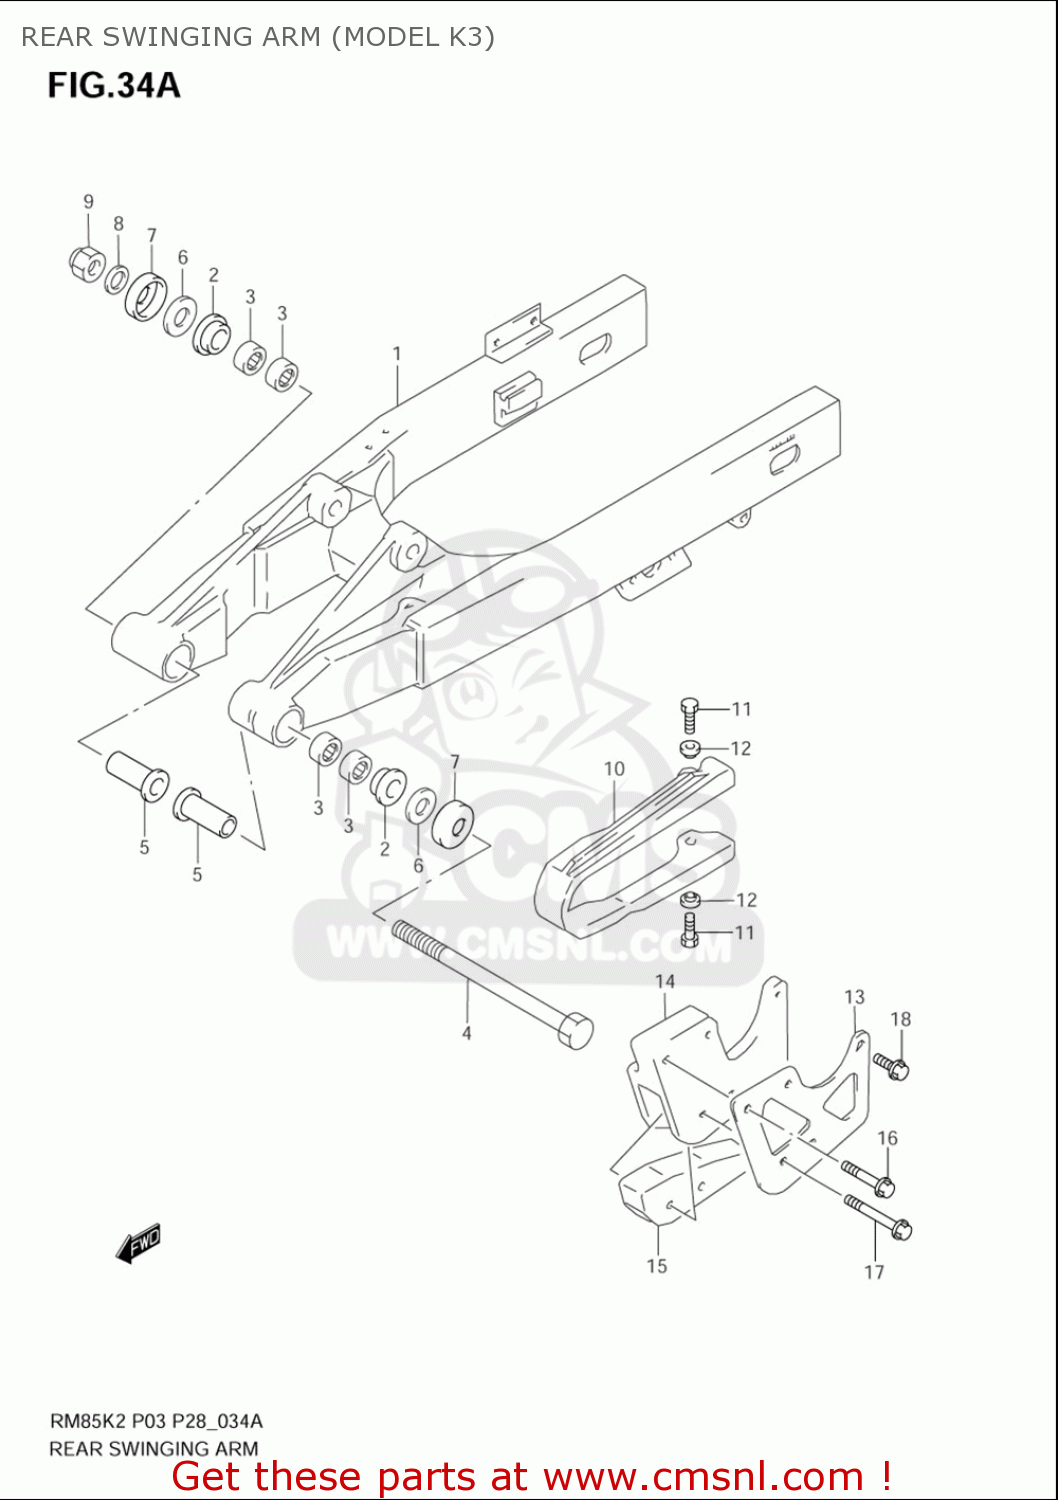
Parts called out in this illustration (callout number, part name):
1	SWINGINGARM ASSY,RR
2	BUSHING,SWGARM PIVOT
3	BEARING(17X24X20)
4	SHAFT,RR SWINGINGARM PIVOT
5	SPACER,RR SWGARM PIVOT
6	WASHER
7	COVER,SWGARM PIVOT
8	WASHER
9	NUT 12MM
10	BUFFER,CHAIN TOUCH DEFENSE
11	BOLT(6X16)
12	WASHER
13	PLATE,GUIDE CHAIN OUTER
14	GUIDE,CHAIN
15	DEFENSE,CHAIN GUIDE
16	BOLT(6X30)
17	BOLT(6X40)
18	BOLT(6X16)
